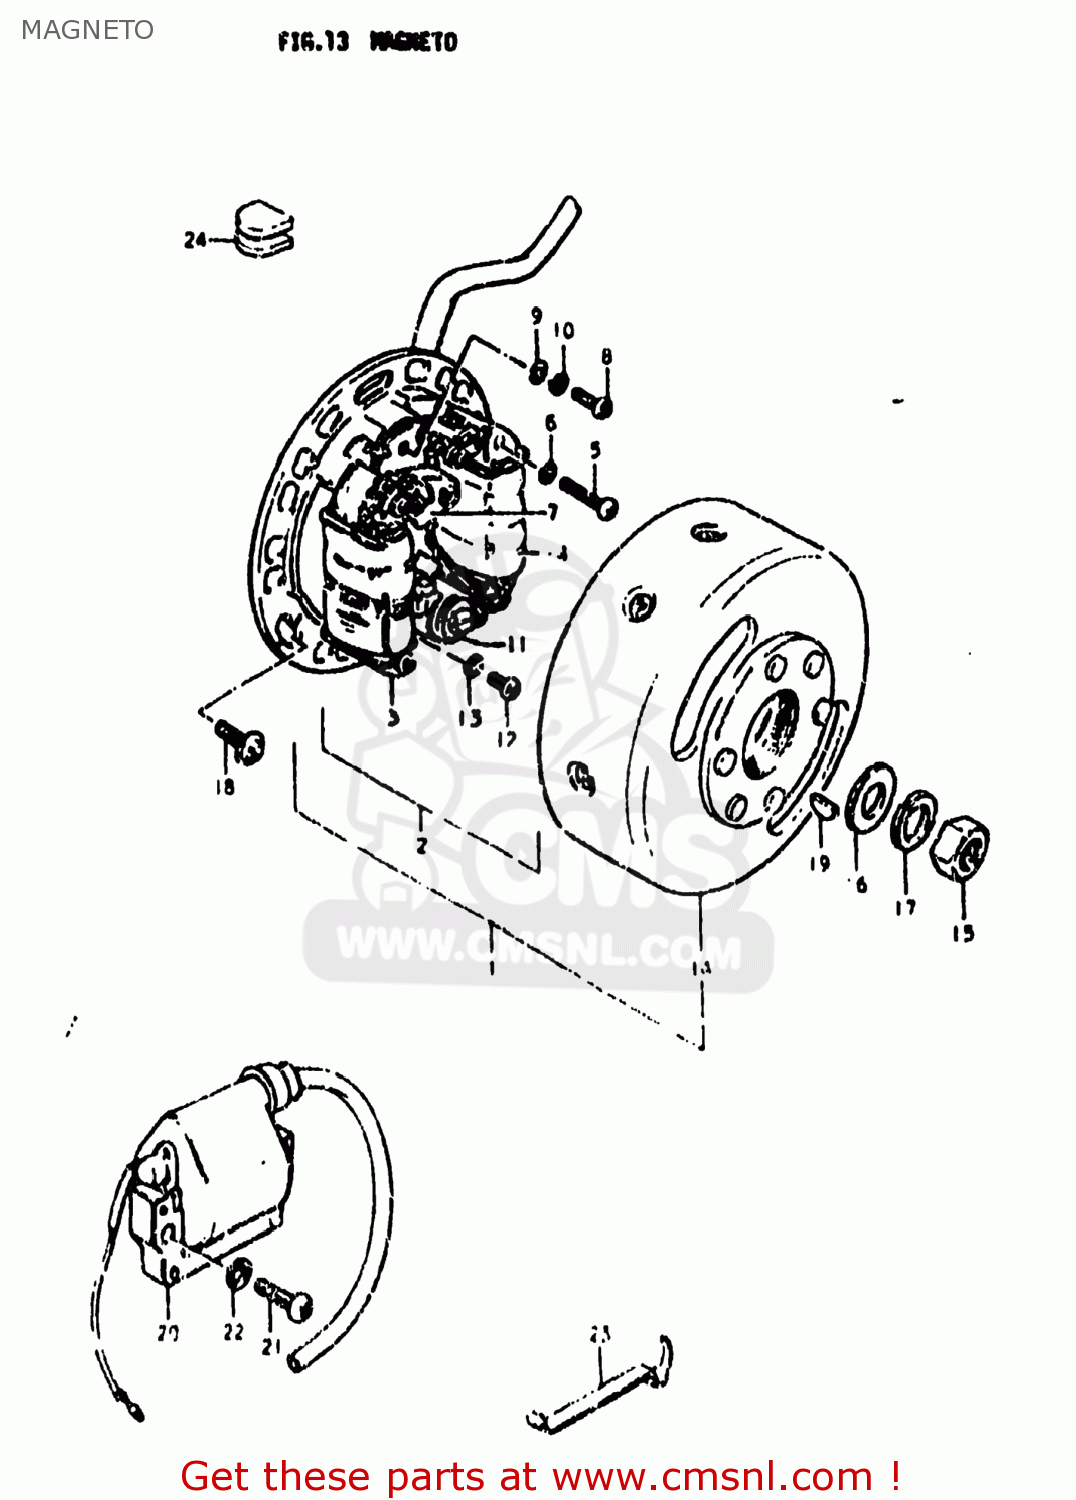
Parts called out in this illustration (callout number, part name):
1	MAGNETO ASSEMBLY
2	STATOR ASSEMBLY
3	COIL,LIGHTING
4	COIL,PRIMARY
5	SCREW
6	LOCK WASHER
7	POINT ASSY,CONTACT
8	SCREW(4X10)
9	WASHER
10	LOCK WASHER
11	CONDENSER
12	SCREW
13	LOCK WASHER
14	ROTOR ASSEMBLY
15	NUT (10MM)
16	WASHER
17	LOCK WASHER
18	SCREW(5X14)
19	KEY
20	COIL ASSEMBLY,IGNITION
21	SCREW
22	LOCK WASHER
23	BAND
24	PLUG
